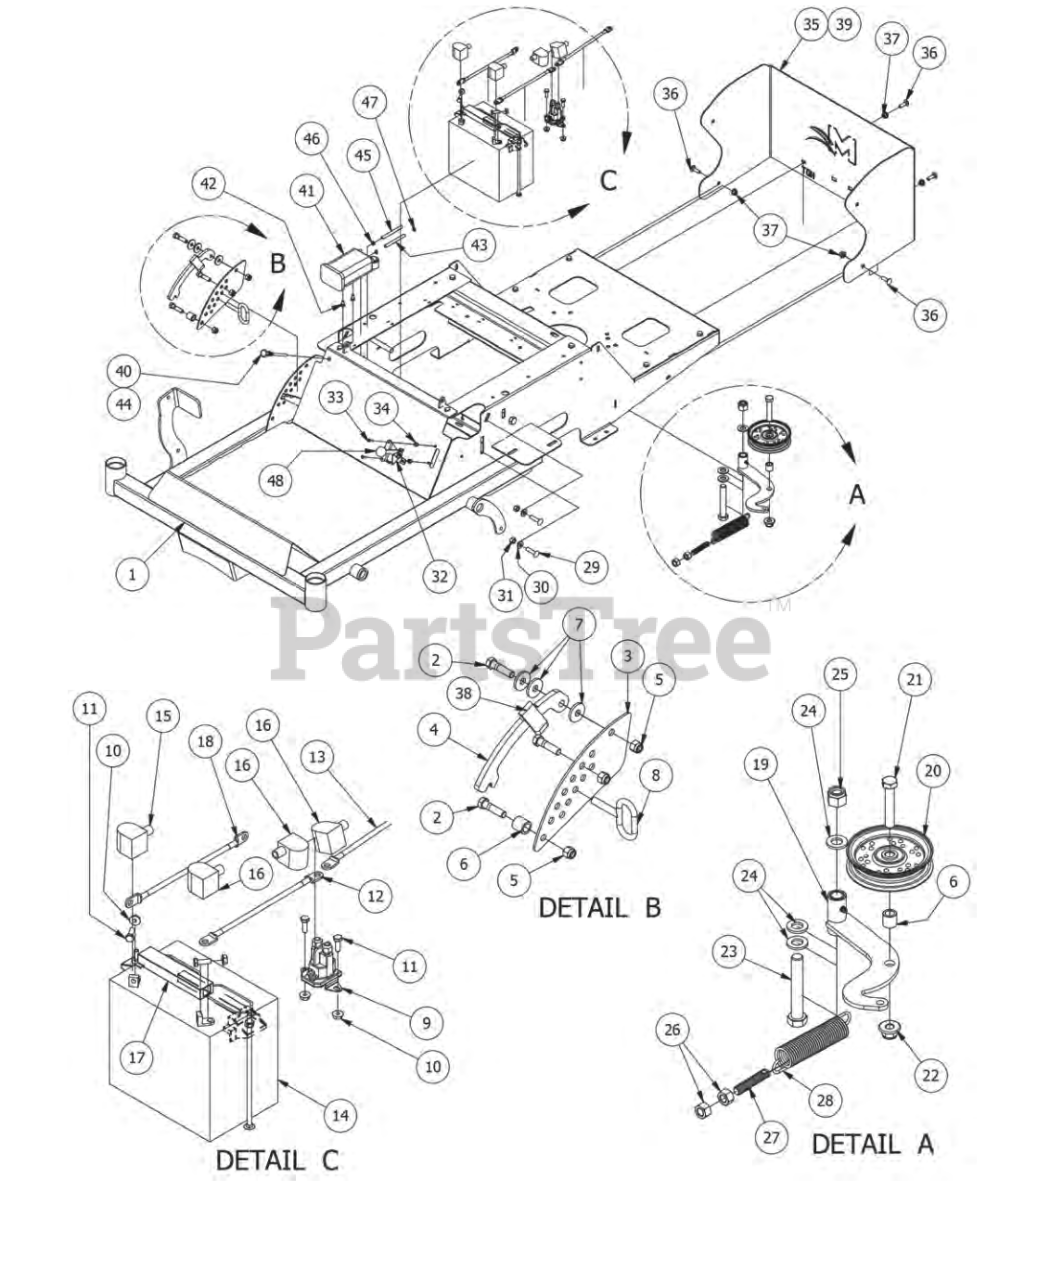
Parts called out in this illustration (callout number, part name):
2	3/8" x 1 1/2" Hex Bolt
3	MZ Height Indicator Plate
4	MZ Deck Level Lock Lever
5	3/8 Nylock Nut
6	3/4 OD x 1/2 ID x 3\4 Length
7	.390 ID Plastic Washer
8	Deck height lever pin
10	1/4-20 Hex Flange Nuts Zinc w/Serrations
11	1/4-20 x 3/4 GR 5 Hex Bolts Zinc
12	10" red battery cable
13	62" red cable
15	Black Boot For ground cable
17	Battery Hold Down
18	24" Ground Cable
19	MZ Idler arm Bracket
20	4 3/4 Idler Pulley - ABFI-76
21	1/2" x 2 3/4" Hex Bolt
22	1/2-13 Nylon Flange Nut-Orange
23	5/8" x 4" Hex Bolt
24	.635 ID Plastic Washer
25	5/8 Std NC Nylock Nut
26	1/2" Hex Nut
27	All Thread-pump Idler Tensioner
28	Deck spring big diameter
29	3/8-16 x 1-1/2 short neck bolt
30	3/8" Flat Washer
31	3/8" Hex Nut
32	Brake cable for MZ
33	10-24 X 5/8 BS C/S 18-8 SS
34	10-24 Nylon Insert Locknut
35	MZ Back Plate
36	5/16" x 1" Carriage Bolt
37	5/16" Flange Nut Zinc W/Serrations
38	Deck Height Handle Grip MZ
39	MZ Engine Rear Plate (21hp)
41	Carbon Canister for Magnum/MZ
42	M6-1.0 X 12MM Bolt 8.8
43	3/16 vinyl tubing
44	Choke Kohler engine
45	1/4" vinyl tubing
46	1/4" vinyl clamp
47	3/16" Vinyl Hose Clamp
48	Universal Throttle Head
